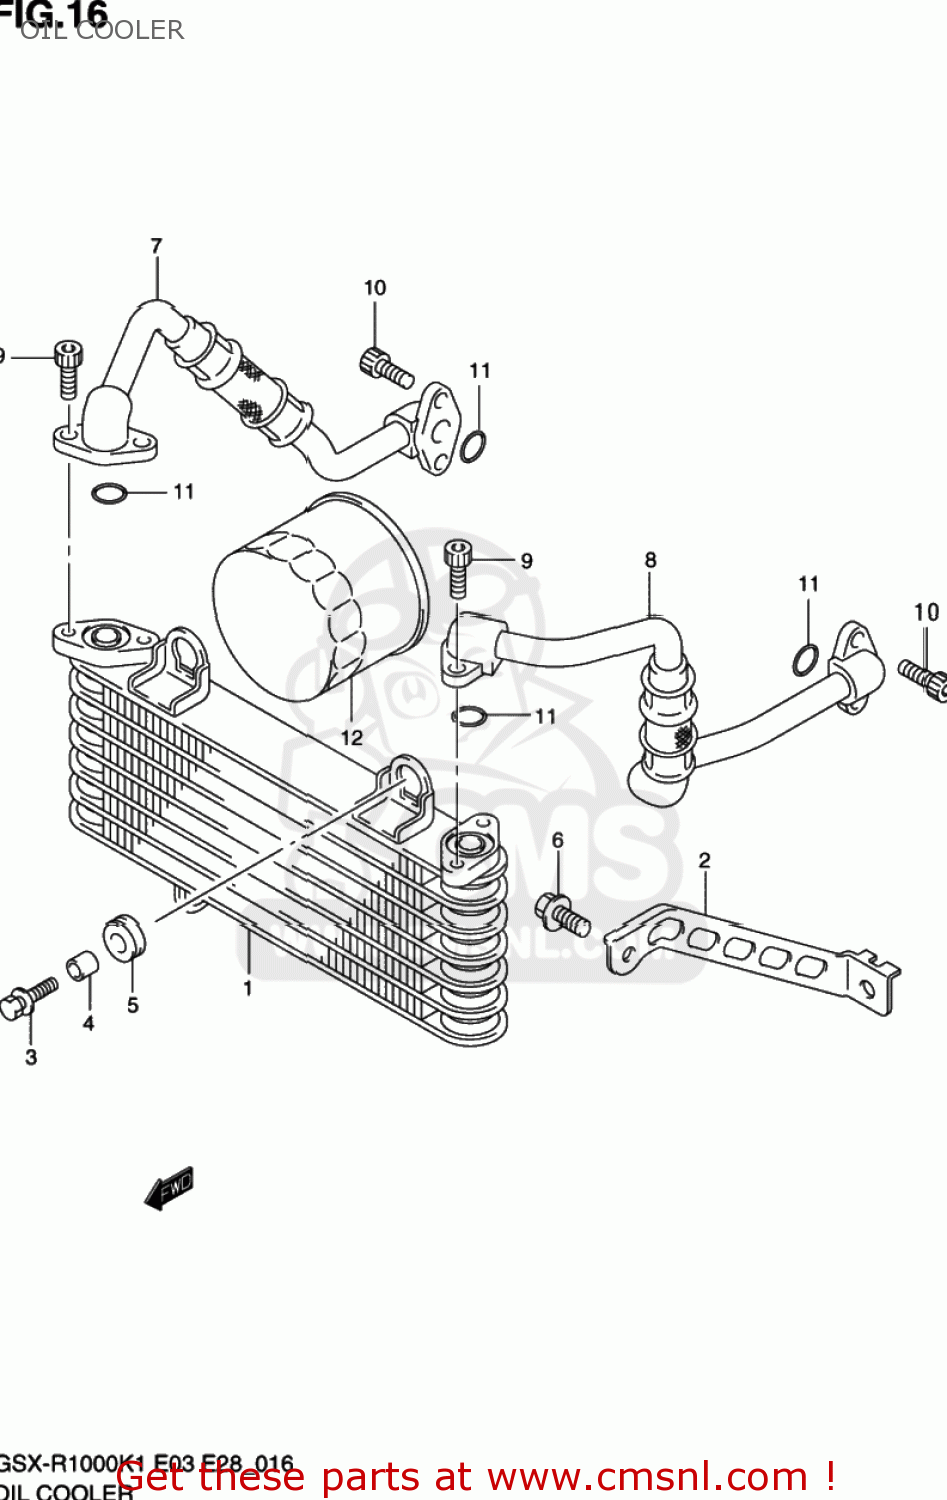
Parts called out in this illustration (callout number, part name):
1	COOLER ASSY,OI
2	BRACKET,OIL COOLER
3	BOLT(6X20)
4	SPACER(6.5X10X10)
5	CUSHION
6	BOLT
7	HOSE COMP,OIL
8	HOSE,OIL COOLER,L
9	BOLT(6X20)
10	BOLT(6X16)
11	O RING(D:2.4,ID:11.8)
12	FILTER ASSEMBLY,ENGINE OIL
